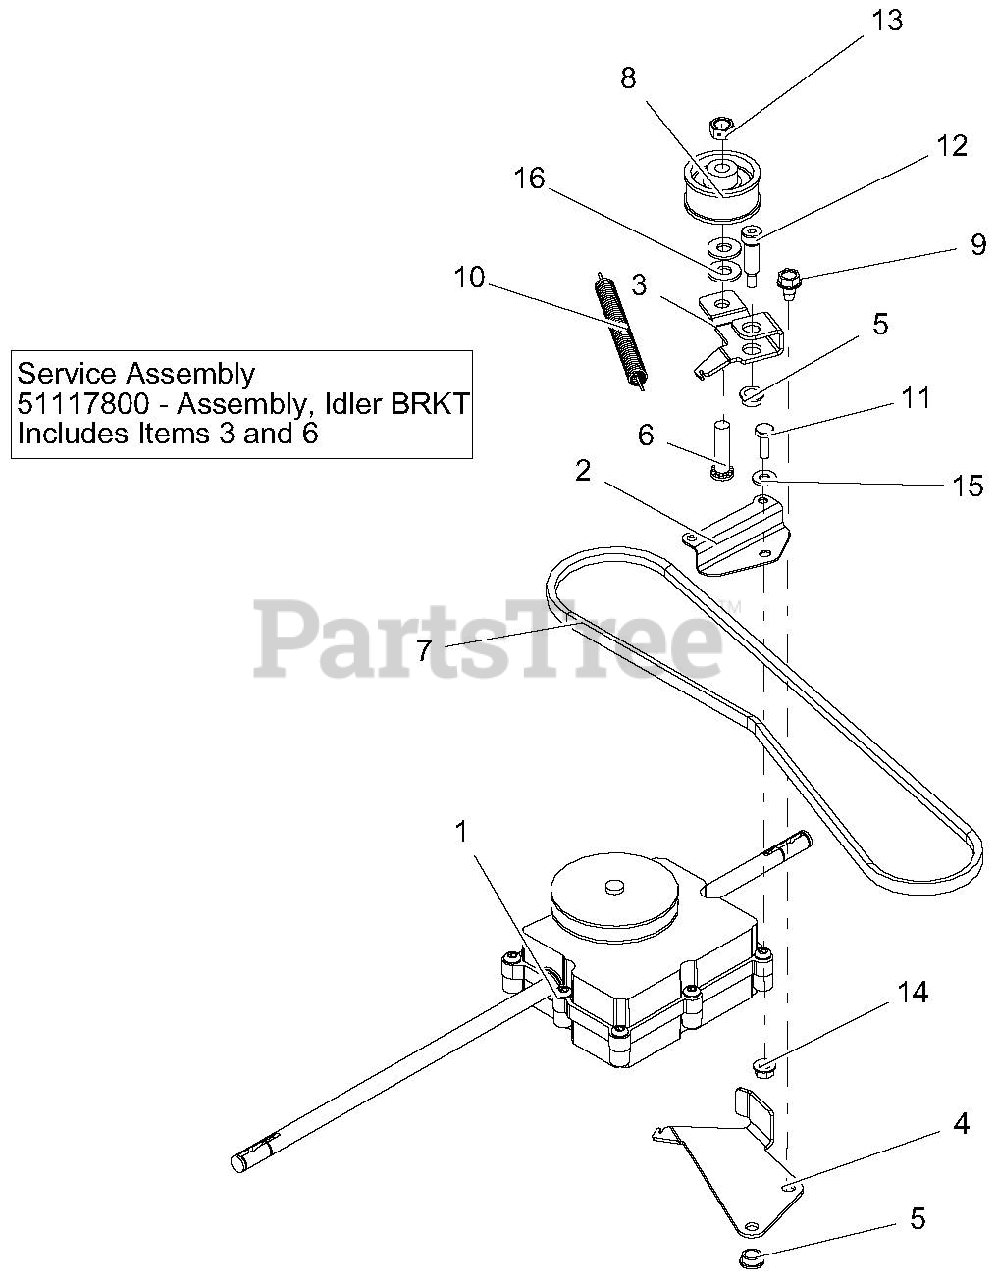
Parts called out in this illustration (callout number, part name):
1	TRANS, 21" MOWER, 3 SPD
2	BRKT, TRANS
3	ARM, IDLER
4	BRKT, IDLER
5	BSHG, IDLER ARM
6	BOLT, STUD
7	V-BELT, 3L SECTION
8	IDLER, FLAT 1.875 OD X .75 WIDE
9	SCR-TAP .31-18X.50 HWH TR YWZ
10	SPRG, EXTENSION
11	BLT-HEX .25-20X.75 GR5 YWZC
12	BLT-SHLDR .375X1.00X.25-20
13	NUT-LK-CTR .38-16 YWZC
14	NUT, LK-TOP-FLG .25-20 YWZC
15	WSHR-FL-STL.281X.62X.065 YWZC
16	WSHR-FL-STL.38X.875X.083 YWZC
17	ASSEMBLY, IDLER BRKT
